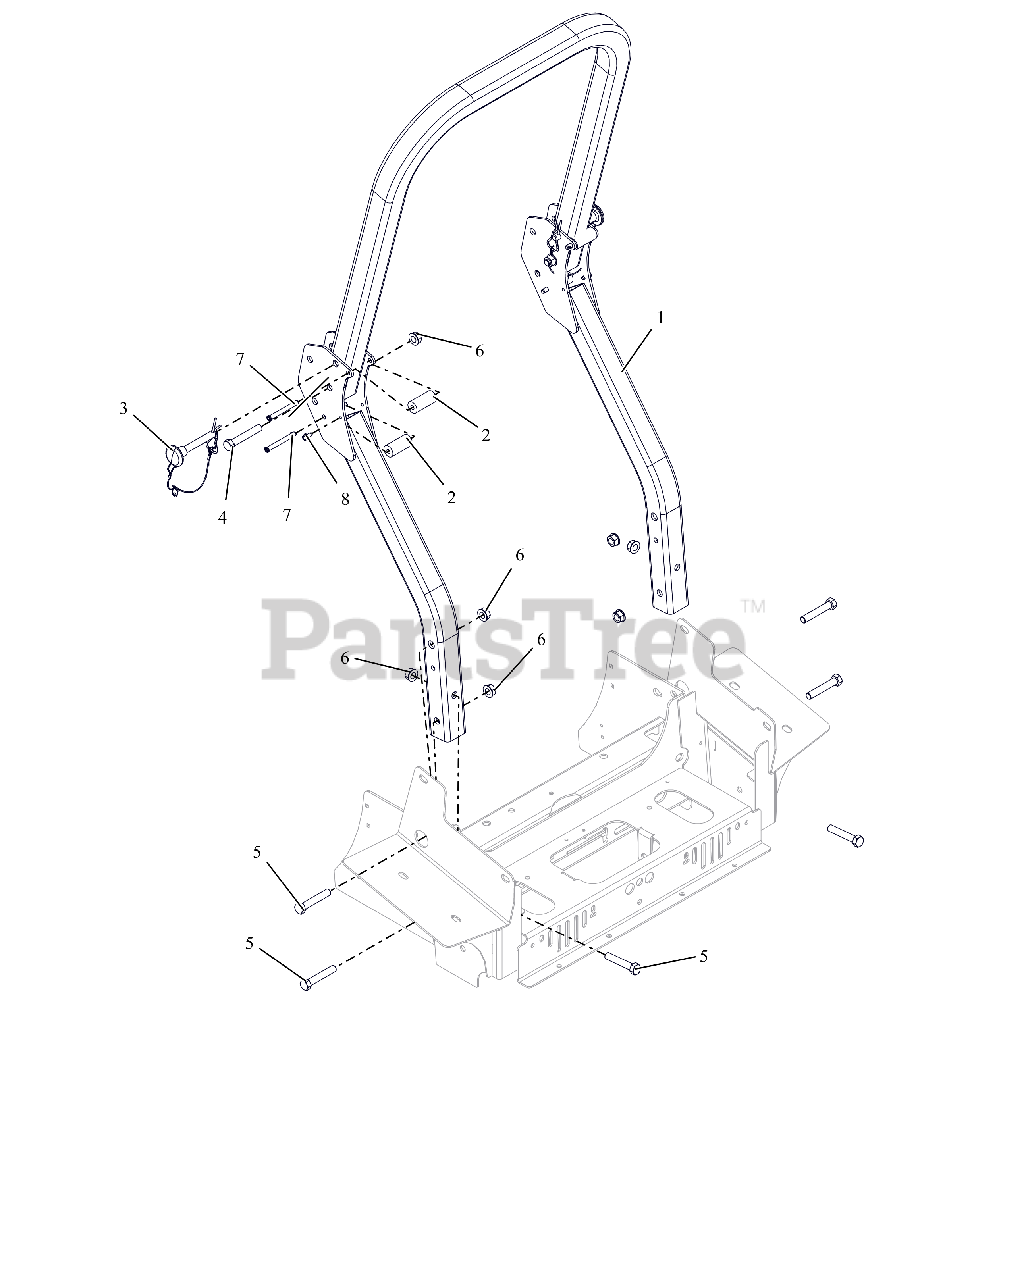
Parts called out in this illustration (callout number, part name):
1	ROPS, PT200/400 REPLACEMENT
2	BUMPER, ROPS ANTI-VIBRATION
3	PIN, ROPS W/LANYARD
4	BLT, HEX .50-13X3.00 G5 ZCC
5	BLT,HEX .50-13X2.75 G5 ZCC
6	NUT-LK-CTR-FLG .500-13 GG ZCC
7	PIN, SLIC .312 X 2.570
8	SCR-TAP .25-20X.50 HWH TR YWZ
